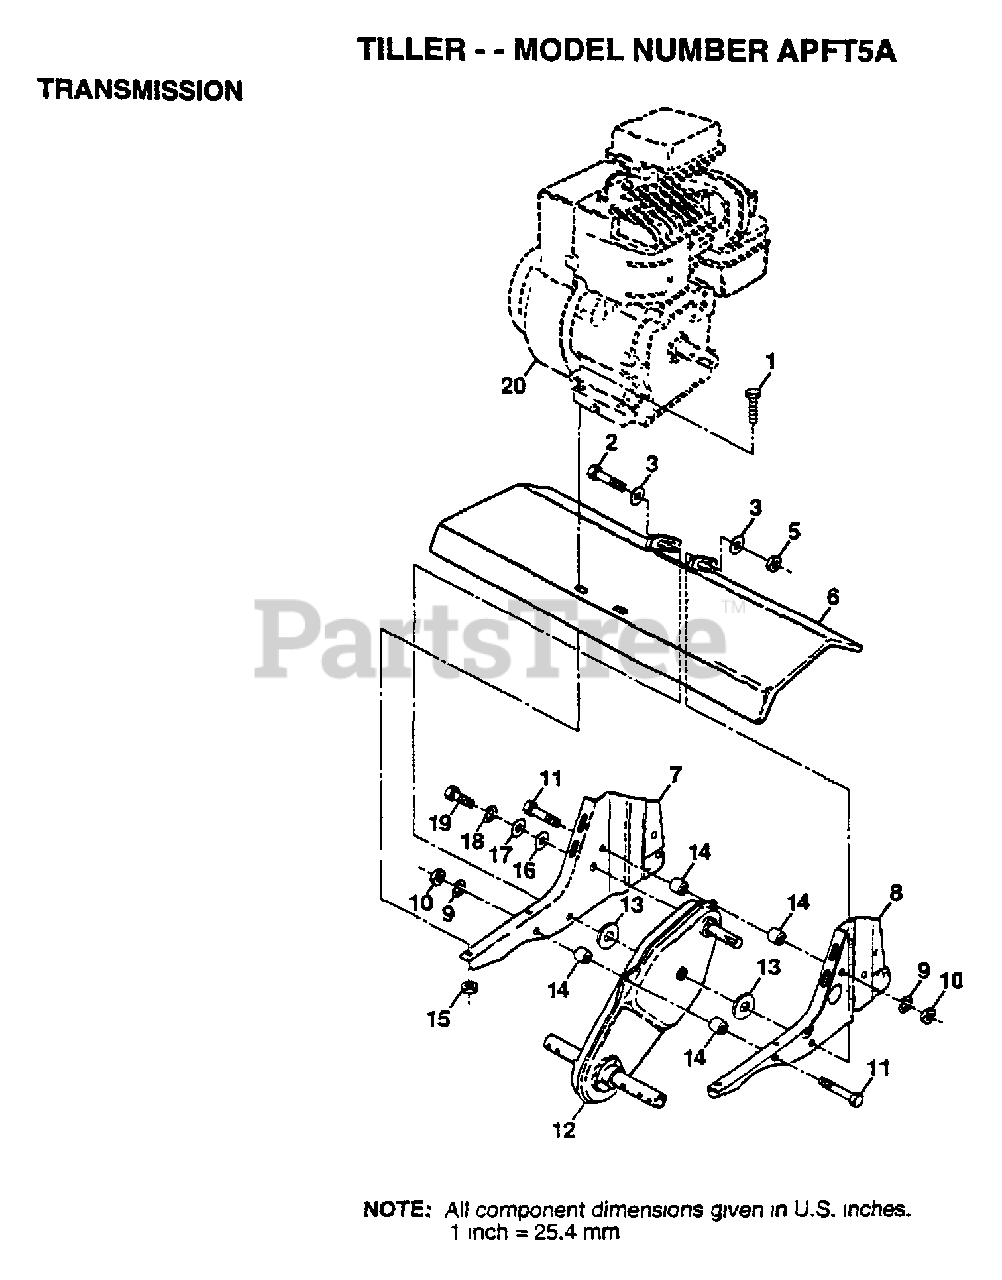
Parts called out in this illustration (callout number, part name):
1	BOLT.HEX.5/16-1.5
2	BOLT HEX 3/8-16
3	WASHER
5	NUT
6	"SHIELD, TINE"
9	LOCKWASHER
10	NUT.HEX.5/16-18
14	SPLIT SPACER RT
16	WASHER
17	WASHER
18	LOCKWASHER
19	BOLT
